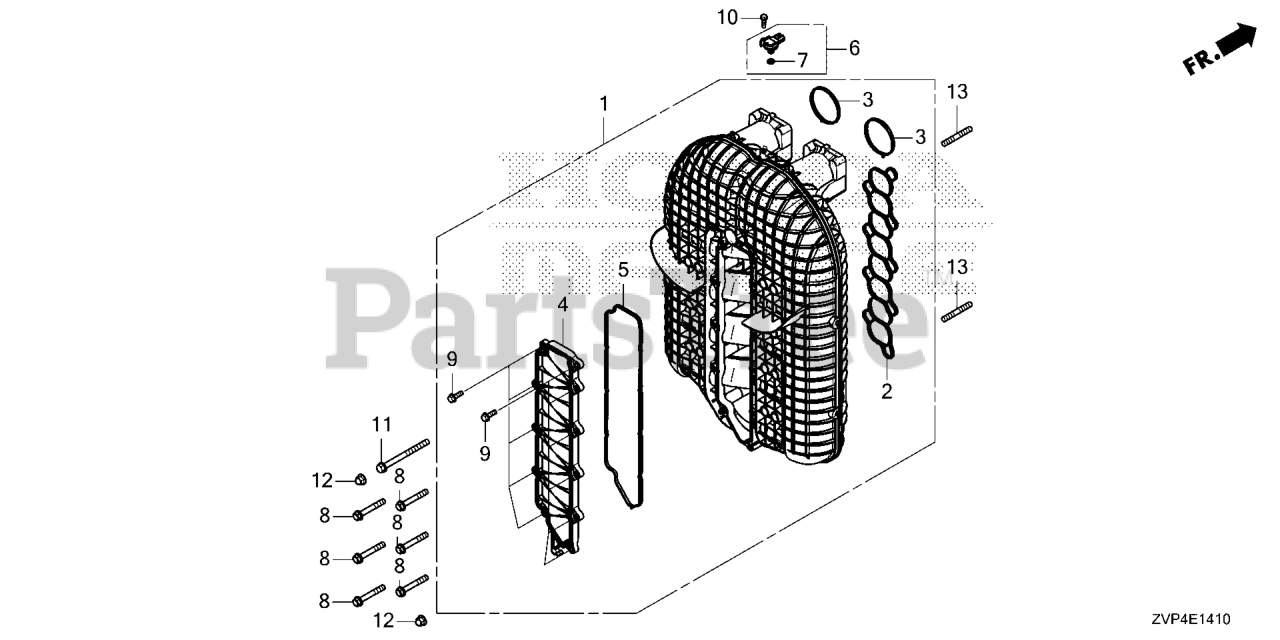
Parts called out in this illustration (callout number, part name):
1	MANIFOLD, INLET
2	PKG, IN MNFLD
3	PKG, THROTTLE BODY
4	CVR, INMNFLD (UPPER)
5	PKG, IN MNFLD
6	SENSOR ASSY., MAP
8	BOLT, FLANGE (8X55)
9	BOLT, FLANGE (6X20)
10	BOLT-WASHER (5X18)
11	BOLT, FLANGE (8X100)
13	BOLT, STUD (8X45)
